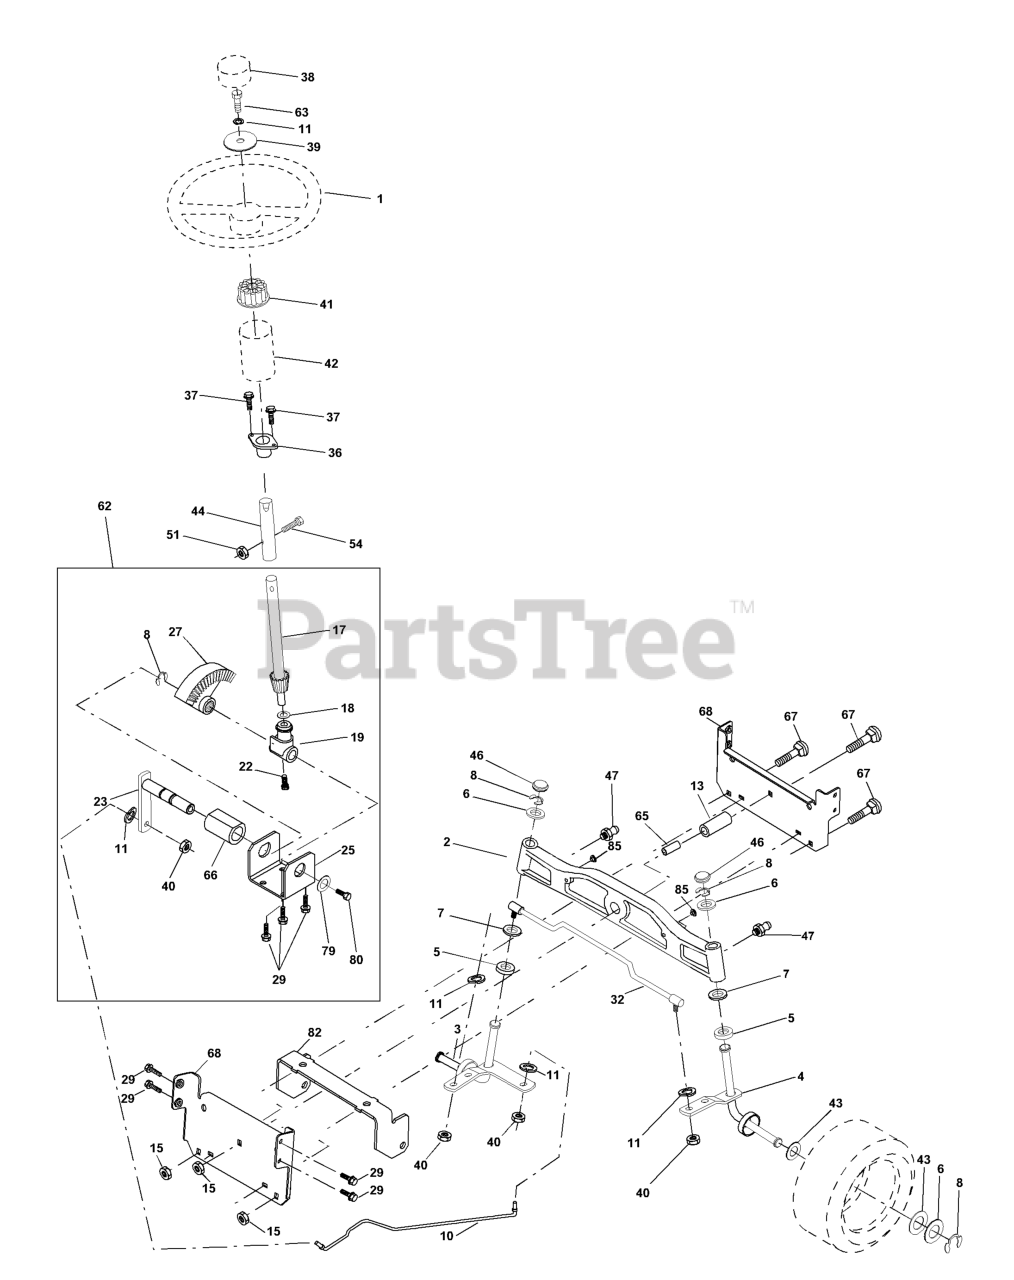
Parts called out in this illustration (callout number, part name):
1	STEERING WHEEL
2	AXLE
3	SPINDLE.ASM.LH.15"TIRES
4	SPINDLE.ASM.RH.15"TIRES
5	THRUST WASHER
6	WASHER
7	WASHER
10	DRAGLINK.15".TIRES
11	WASHER
13	TUBE, PIVOT AXLE
15	NUT
17	SHAFT ASM STEERING
18	THRUST WASHER
19	STEERING SHAFT SUPPORT
22	SCREW
23	SHAFT ASSY PITTMAN
25	BRACKET STEERING
27	GEAR.SECTOR
29	SCREW
32	ROD.ASM.TIE.BALL.JOINT.NOVAN
36	BUSHING, STEERING
37	SCREW
38	CAP.WHEEL.STEERING.GREY
39	WASHER 13/32 X 1-1/20 X 11 GA.
40	LOCK NUT
41	STEERING WHEEL ADAPTOR
42	BOOT STEERING
43	WASHER
44	EXTENTION STEERING
46	CAP.SPINDLE.BLACK
47	ZERK M
51	NUT
54	BOLT
62	STEERING KIT
63	BOLT
65	SPACER BRACE AXLE
66	BEARING ARM
67	BOLT
68	BRACE.AXLE.15"TIRES
79	WASHER
80	BOLT
82	BRACKET
